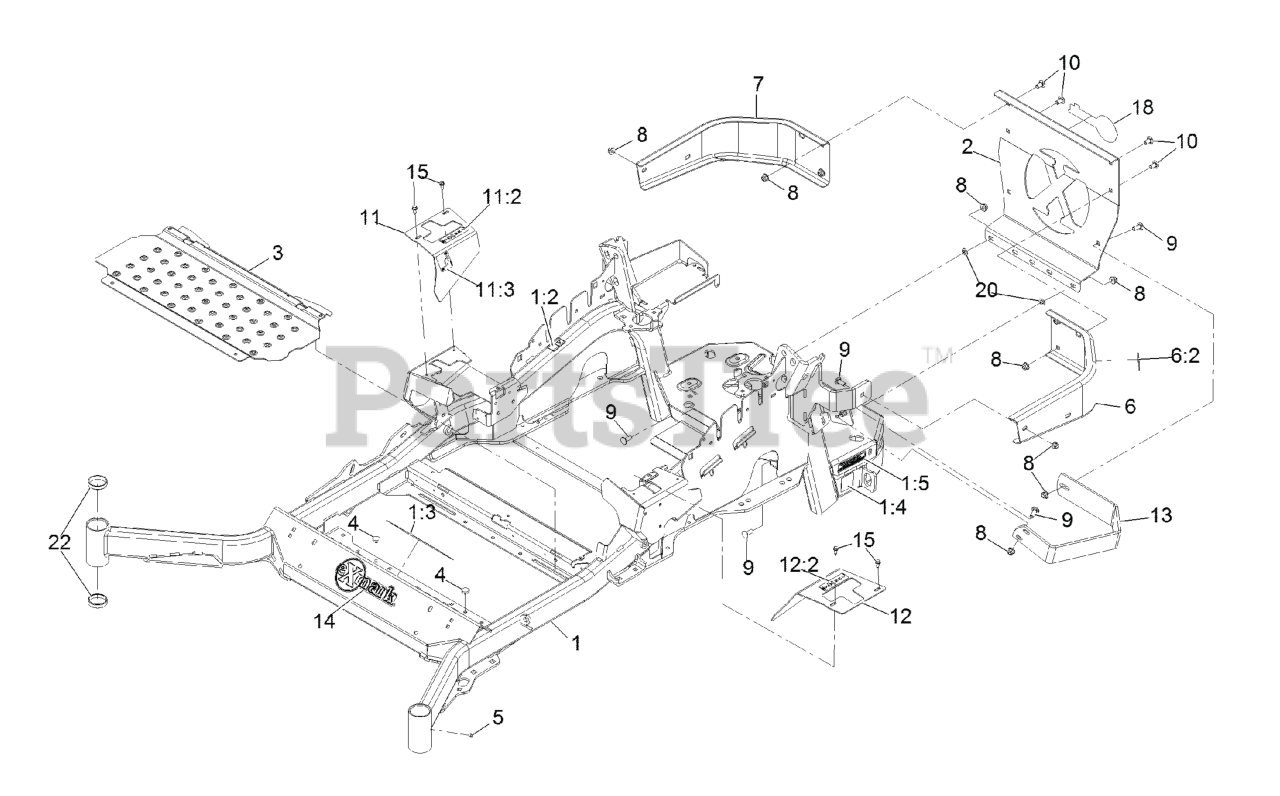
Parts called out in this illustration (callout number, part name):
1	MAINFRAME ASM
1:2	DECAL-WARNING
1:3	DECAL-DANGER
1:4	DECAL-HAZARD, PINCHED FINGER
1:5	DECAL-ARRESTOR, SPARK
2	PLATE,REAR GUARD
6	LH BUMPER ASM
6:2	DECAL-WARNING
7	BUMPER-RH
8	NUT-HF, NI
9	SCREW-CARR
10	SCREW-CARR
11	RH MOTION CONTROL COVER ASM
11:2	DECAL-CONTROL, MOTION
11:3	DECAL-PARK BRAKE, CE
12	LH MOTION CONTROL COVER ASM
12:2	DECAL-CONTROL, MOTION
13	GUARD-MUFFLER
14	DECAL-EXMARK
15	SCREW-HWH
20	NUT-PUSH
22	CUP-BEARING
